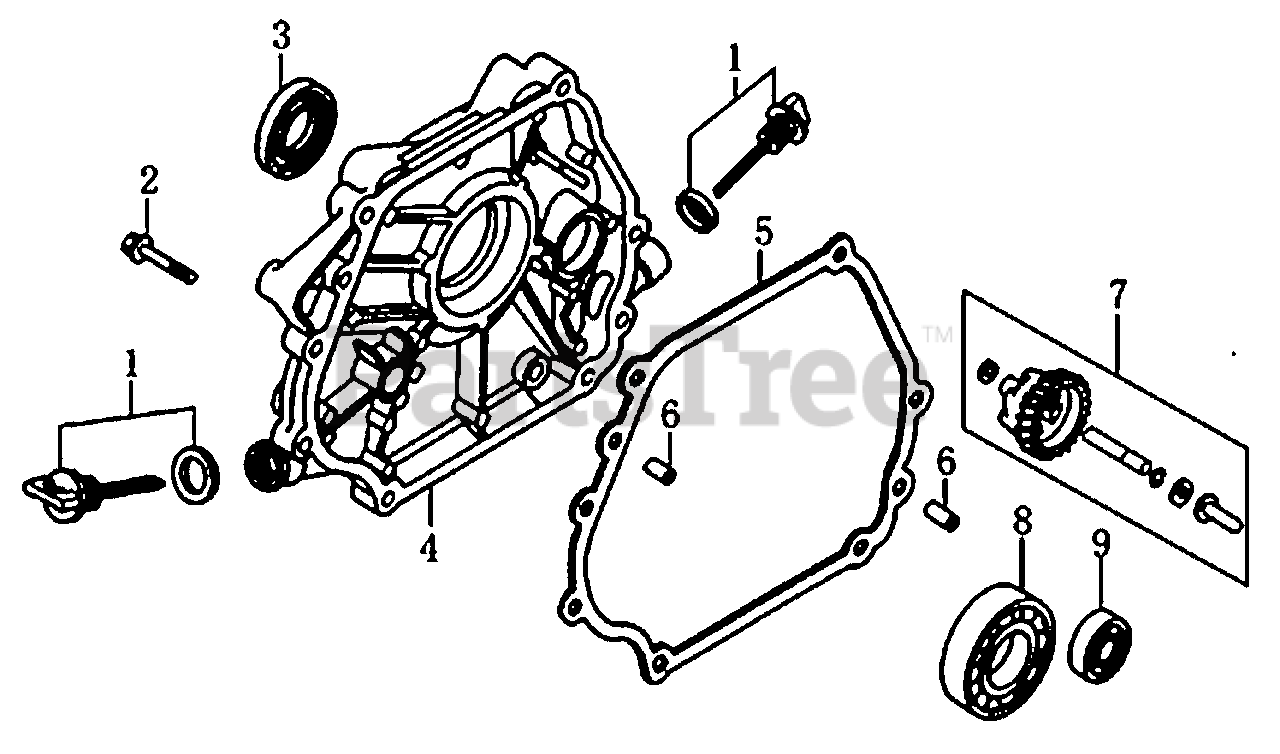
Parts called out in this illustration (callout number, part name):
1	CAP ASSY., DIP STICK
2	BOLT, FLANGE 8X40
3	OIL SEAL 35X52X7
4	CRANKCASE COVER
5	GASKET, CRANKCASE COVER
6	DOWEL PIN 8X12
7	GOVERNOR ASSY.
8	BALL BEARING 6207
9	BALL BEARING 6202
